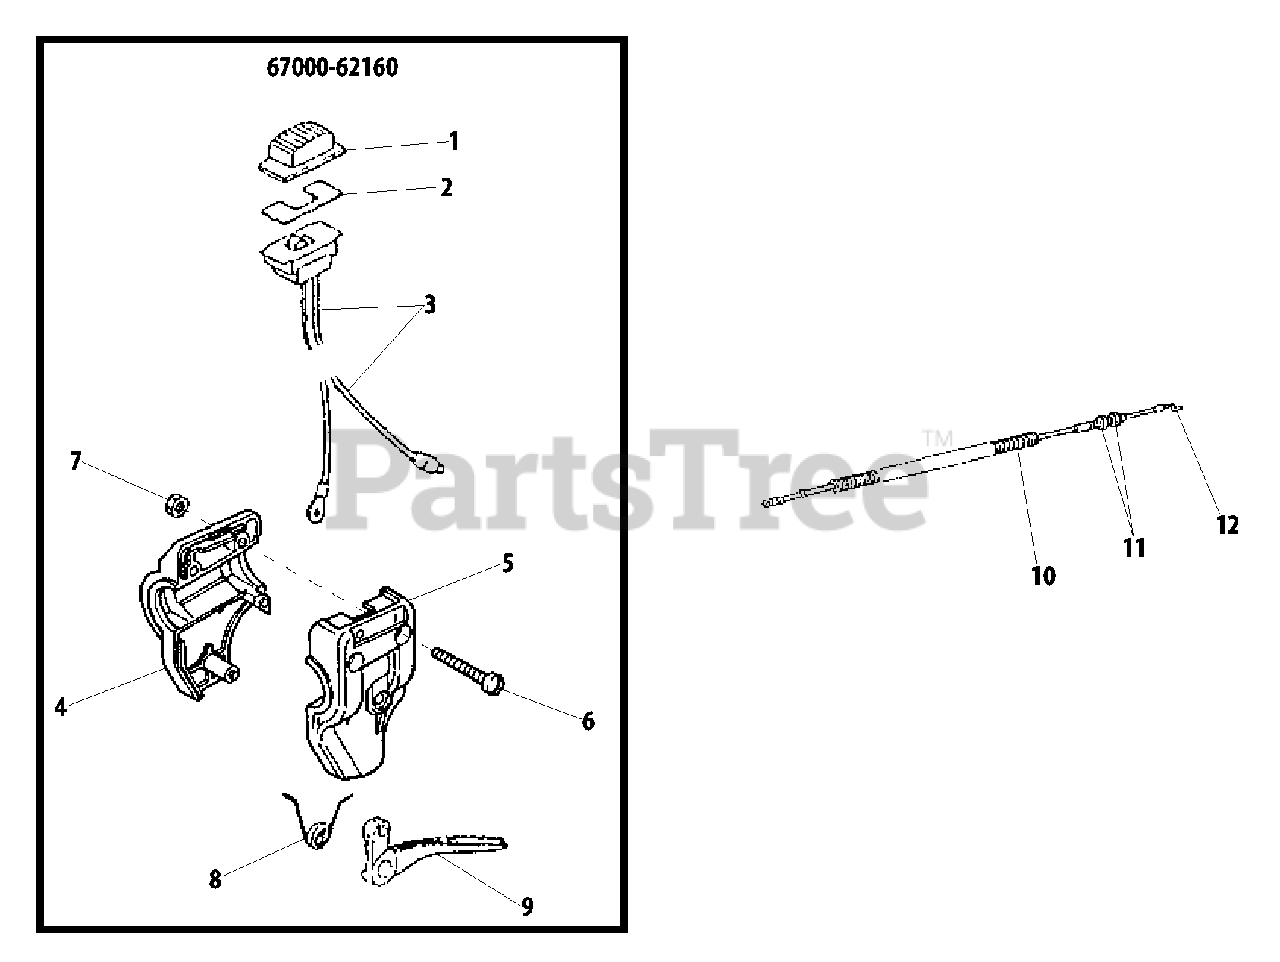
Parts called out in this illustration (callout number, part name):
1	KNOB
2	PLATE, SWITCH
3	SWITCH, IGNITION
4	BRACKET - RIGHT
5	BRACKET - LEFT
6	SCREW - 5X30
7	NUT - 5
8	SPRING, TRIGGER
9	TRIGGER, THROTTLE
10	TUBE
11	NUT - 6
12	CABLE, THROTTLE
67000-62160	THROTTLE LEVER ASSY
